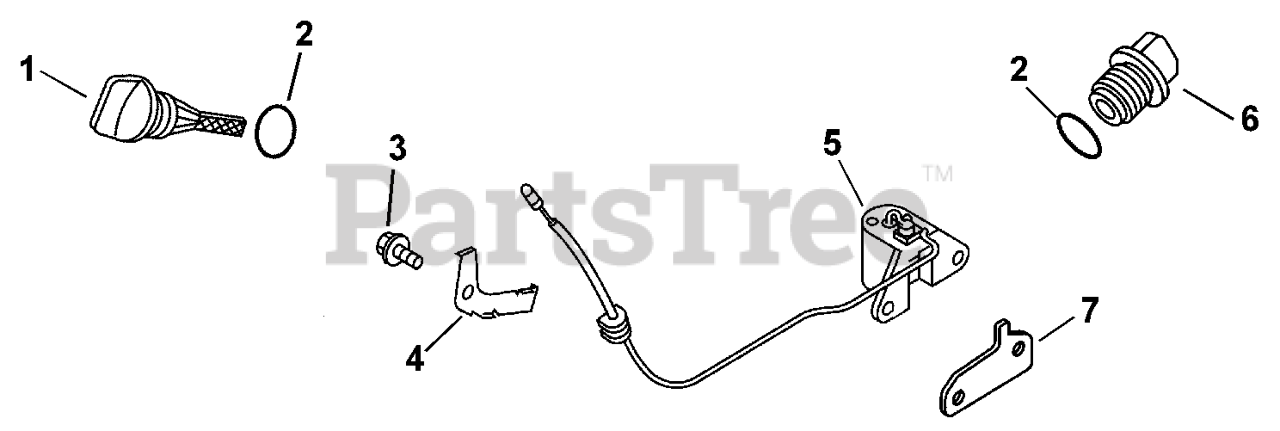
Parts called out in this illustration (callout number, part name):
1	PLUG, OIL LEVEL
2	O-RING, PLUG
5	SWITCH, OIL LEVEL
6	PLUG, OIL
